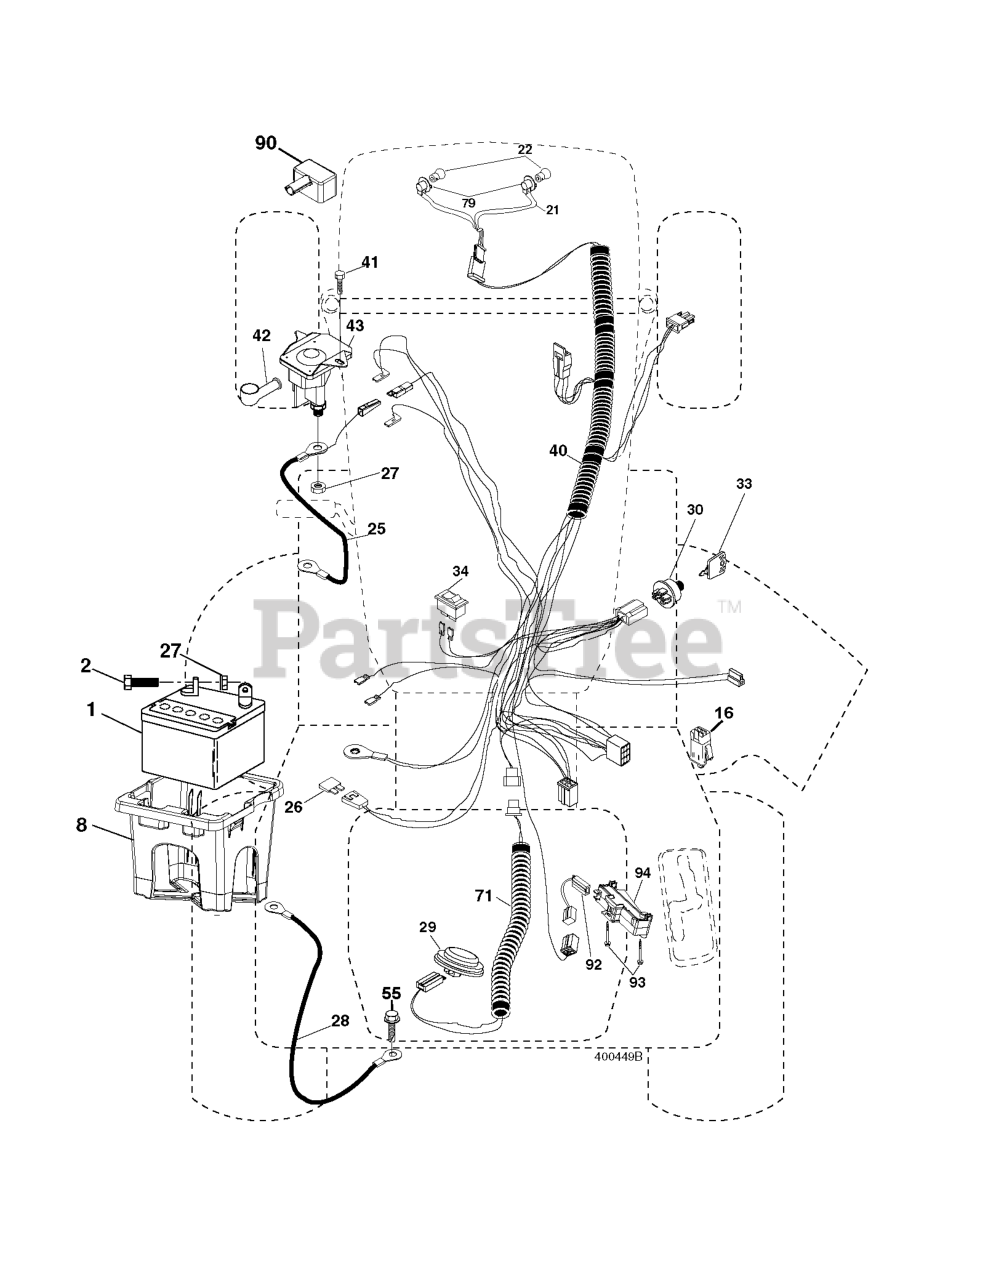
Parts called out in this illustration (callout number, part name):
1	BATTERY 12V .35 AMP
2	BOLT.HEX.1/4.X.3/4.DICHROMATE
8	BOX.BATTERY.MNT.REAR.L
16	SWITCH INTERLOOK PUSH-IN
21	HARNESS.LIGHT W/4152J BULBS
25	CABLE.STARTER.6GA.RED.
26	FUSE 20AMP
27	NUT
28	CABLE.BLACK.18"REAR.BA
29	SWITCH.SEAT.DP W/RAMPS
30	SWITCH.IGN.DELTA.W.LGH.ROS
33	KEY MLD GEN DELTA
40	HARNESS.IGN.CHASS.TEX.REAR.BAT
41	SCREW
42	TERMINAL COVER
43	SOLENOID.W/BRASS.PLUNGER
55	SCREW 5/16"
71	HARNESS IGN. DASH
79	BULB HOLDER ASM.
90	COVER, TERMINAL BATTERY
92	HARNESS.PIGTAIL.CONSLE
93	SCREW.PLASTITE
94	MODULE.REVERSE.ROS
